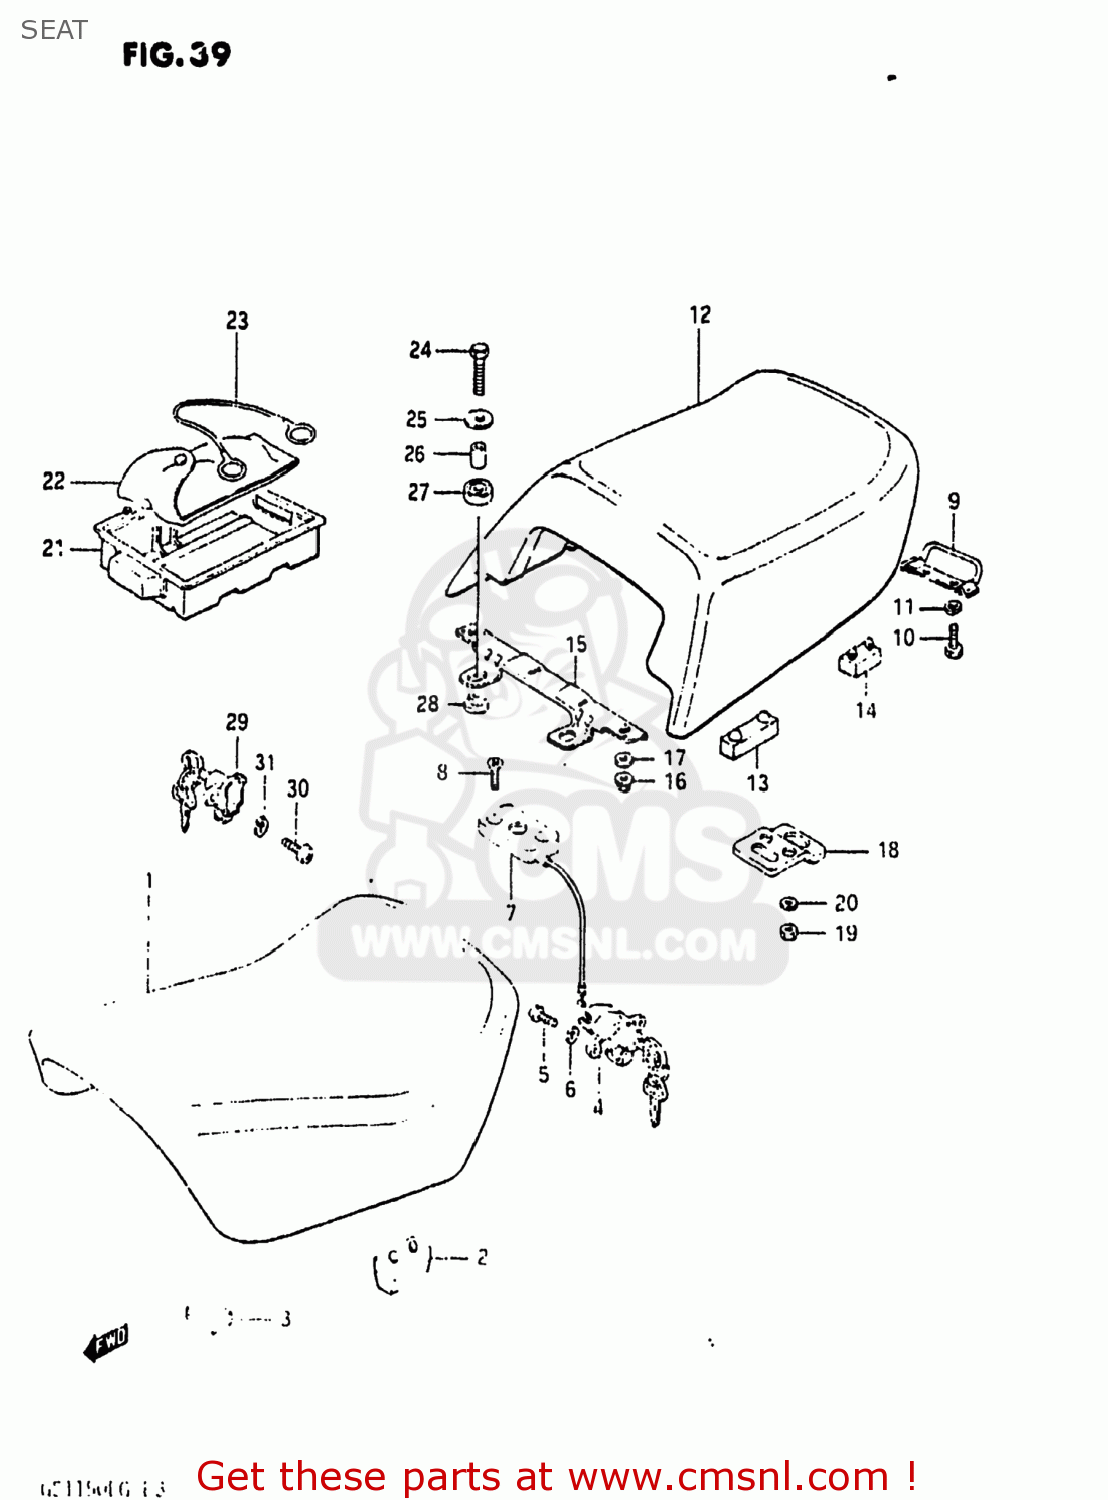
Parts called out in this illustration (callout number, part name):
1	SEAT ASSEMBLY
2	CUSHION,SEAT
3	CUSHION,TOOL(40X30X15)
4	LOCK ASSEMBLY,SEAT & HELMET
5	SCREW
6	WASHER,LOCK
7	BRACKET,SEAT SUPPORT
8	SCREW
9	PLATE,SEAT HOOK,REAR
10	BOLT
11	WASHER,LOCK
12	SEAT ASSEMBLY,PILLION
13	CUSHION,SEAT
14	CUSHION(40X23X12.7)
15	PLATE,PILLION SEAT,FRONT
16	NUT
17	WASHER,LOCK
18	PLATE, SEAT HOOK REAR
19	NUT
20	WASHER,LOCK
21	TOOL BOX
22	TOOL SET
23	BAND,TOOL BOX
24	SCREW(6X30)
25	WASHER (6.5X24X1.6)
26	SPACER
27	CUSHION
28	CUSHION
29	LOCK ASSEMBLY,HELMET
30	SCREW
31	WASHER,LOCK
